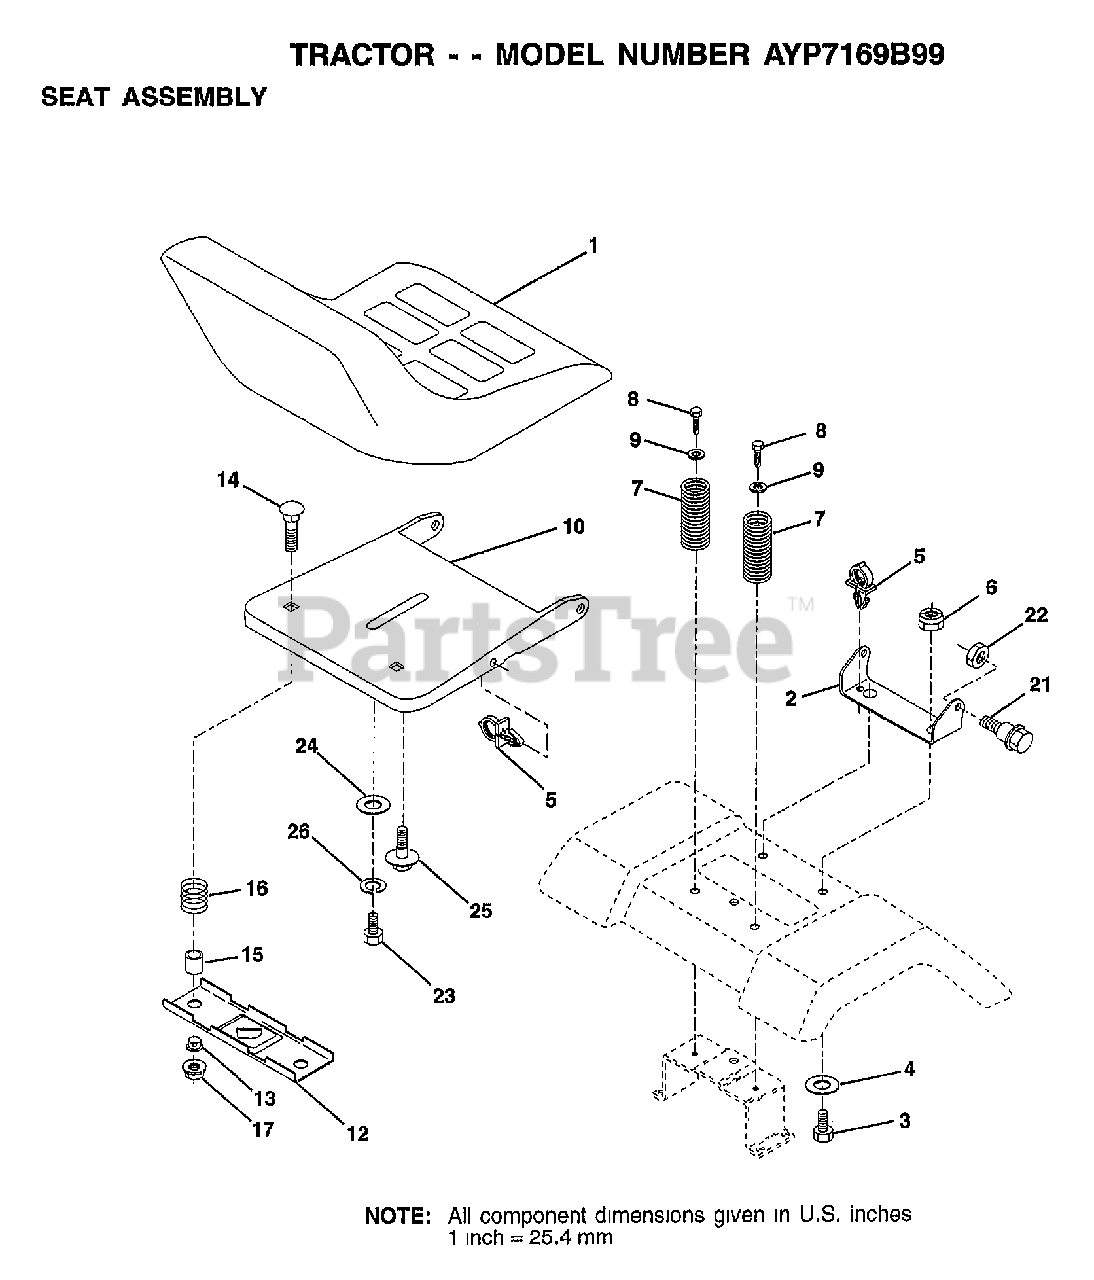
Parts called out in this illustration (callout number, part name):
2	BRACKET PVT SEAT
3	BOLT
4	WASHER PM
5	CLIP.PUSH-IN.HING
6	NUT
7	SPRING COMPRESSIO
8	SCREW
9	WASHER
10	PAN-SEAT
12	BRKT SWITCH
13	BUSHING
14	BOLT-RD HD SQ NK
15	SPLIT SPACER
16	SPRING
21	"BOLT,SHOULDER"
22	NUT
23	BOLT
24	WASHER
25	"BOLT,SHOULDER"
26	LOCKWASHER
